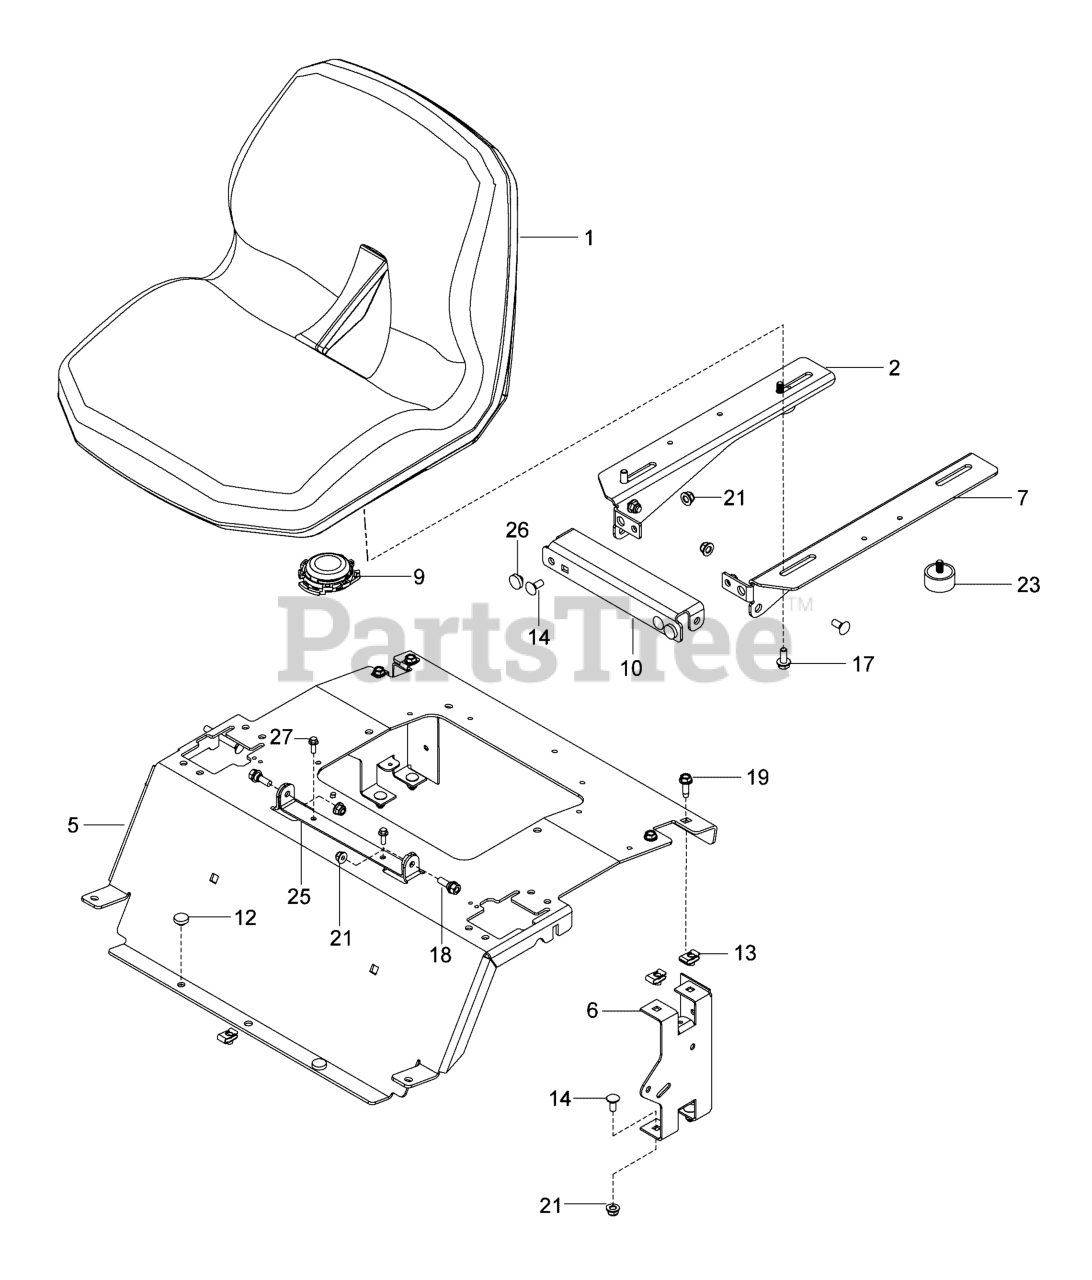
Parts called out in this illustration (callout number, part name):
2	BRACKET, Mounting, Seat, Left
5	SUPPORT, Seat
6	SUPPORT, Seat
7	BRACKET, Mounting, Seat, Right
9	Switch, Seat
10	BRACKET, Mounting, Seat, Front
14	BOLT, 5/16-18 X 3/4 GR. 5 ZD
17	SCREW, Flange, 5/16-18 X 3/4
18	BOLT, 5/16-18
19	SCREW, 5/16-18 x 3/4 Thred Roll
21	LOCKNUT, 5/16-18 HEX FLANGE NYLOC
25	BRACKET, Seat
27	SCREW, 1/4-20 X .75
